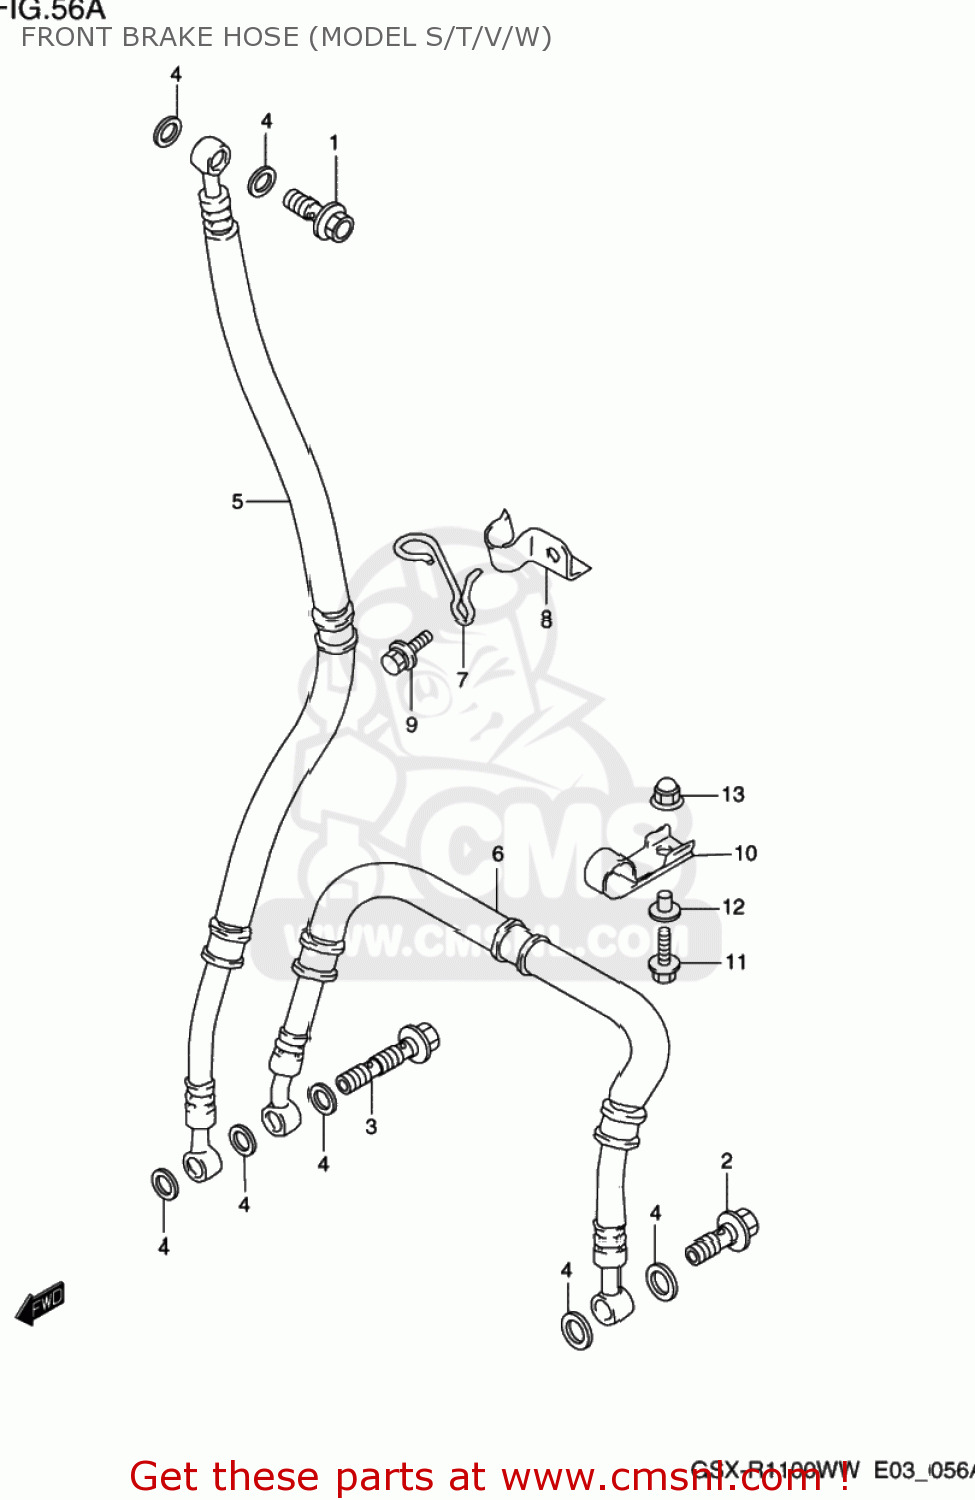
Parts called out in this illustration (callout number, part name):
1	BOLT UNION
2	BOLT UNION
3	BOLT UNION
4	WASHER(10X15X1.5)
5	HOSE COMP,FRONT BRAKE
6	HOSE,FR BRAKE NO.2
7	GUIDE,FR BRAKE HOSE
8	CLAMP,FR BRAKE HOSE UPR
9	BOLT
10	CLAMP,FR BRAKE HOSE NO.2
11	BOLT
12	WASHER
13	NUT
